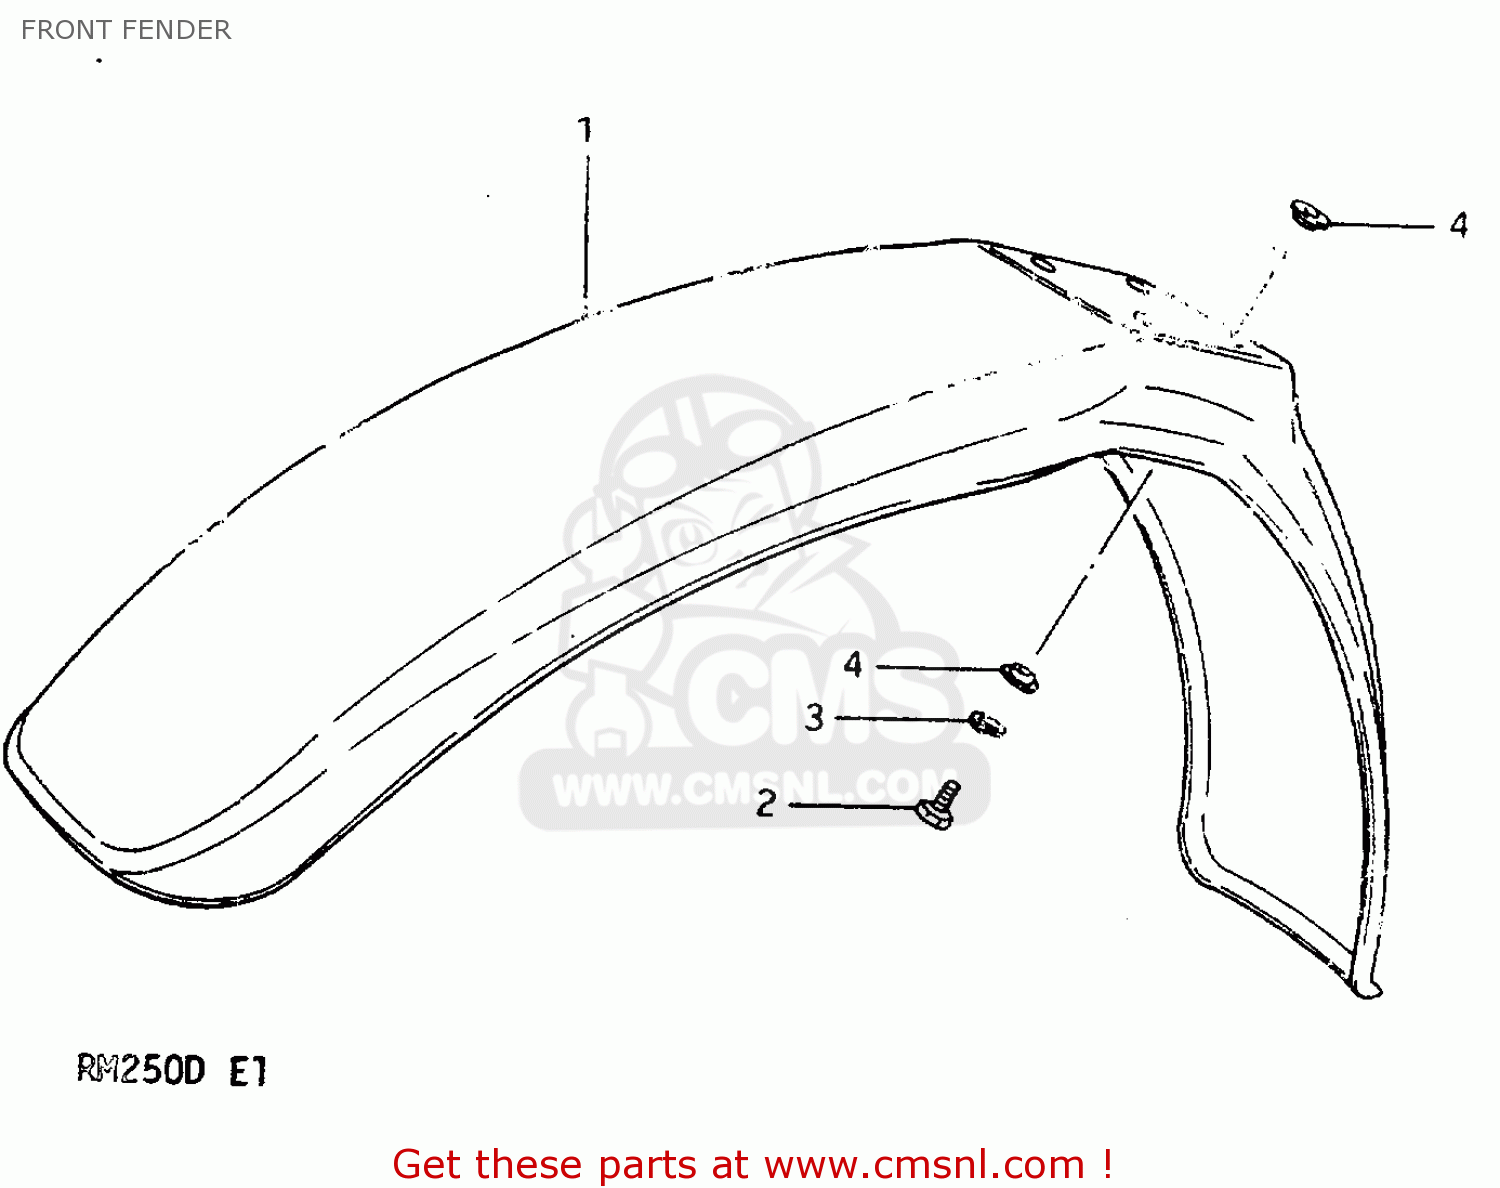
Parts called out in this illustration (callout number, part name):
1	FENDER,FR
2	BOLT
3	WASHER,LOCK
4	WASHER
